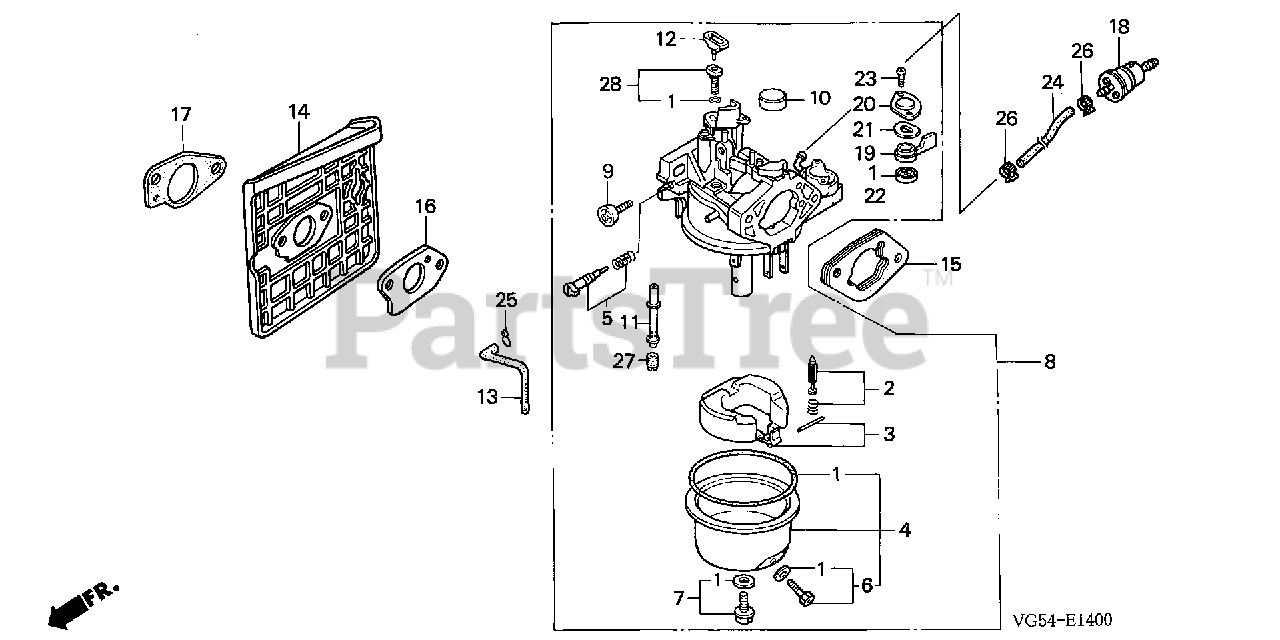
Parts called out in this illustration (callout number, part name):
1	GASKET SET
2	VALVE SET, FLOAT
4	CHAMBER SET, FLOAT
6	SCREW SET, DRAIN
7	SCREW SET B
8	CARBURETOR ASSY. (BE86F B)
9	SCREW, THROTTLE STOP
10	CAP, CHOKE LEVER DUST
11	NOZZLE, MAIN
12	COLLAR, SET
13	TUBE, AIR VENT (75MM)
14	INSULATOR, CARBURETOR
15	SPACER, CARBURETOR
16	GASKET, CARBURETOR
17	GASKET, INSULATOR
18	FILTER, FUEL
19	LEVER, VALVE
20	PLATE, LEVER SETTING
21	SPRING, VALVE LEVER
22	GASKET, VALVE
23	SCREW, PAN (3X6)
24	BULK HOSE, FUEL (4.5X3000) (4.5X360)
25	CLIP, TUBE (B8)
26	CLIP, TUBE (D8.5)
27	JET, MAIN (#88)
27	JET, MAIN (#90)
27	JET, MAIN (#92)
28	JET SET, PILOT (#40)
